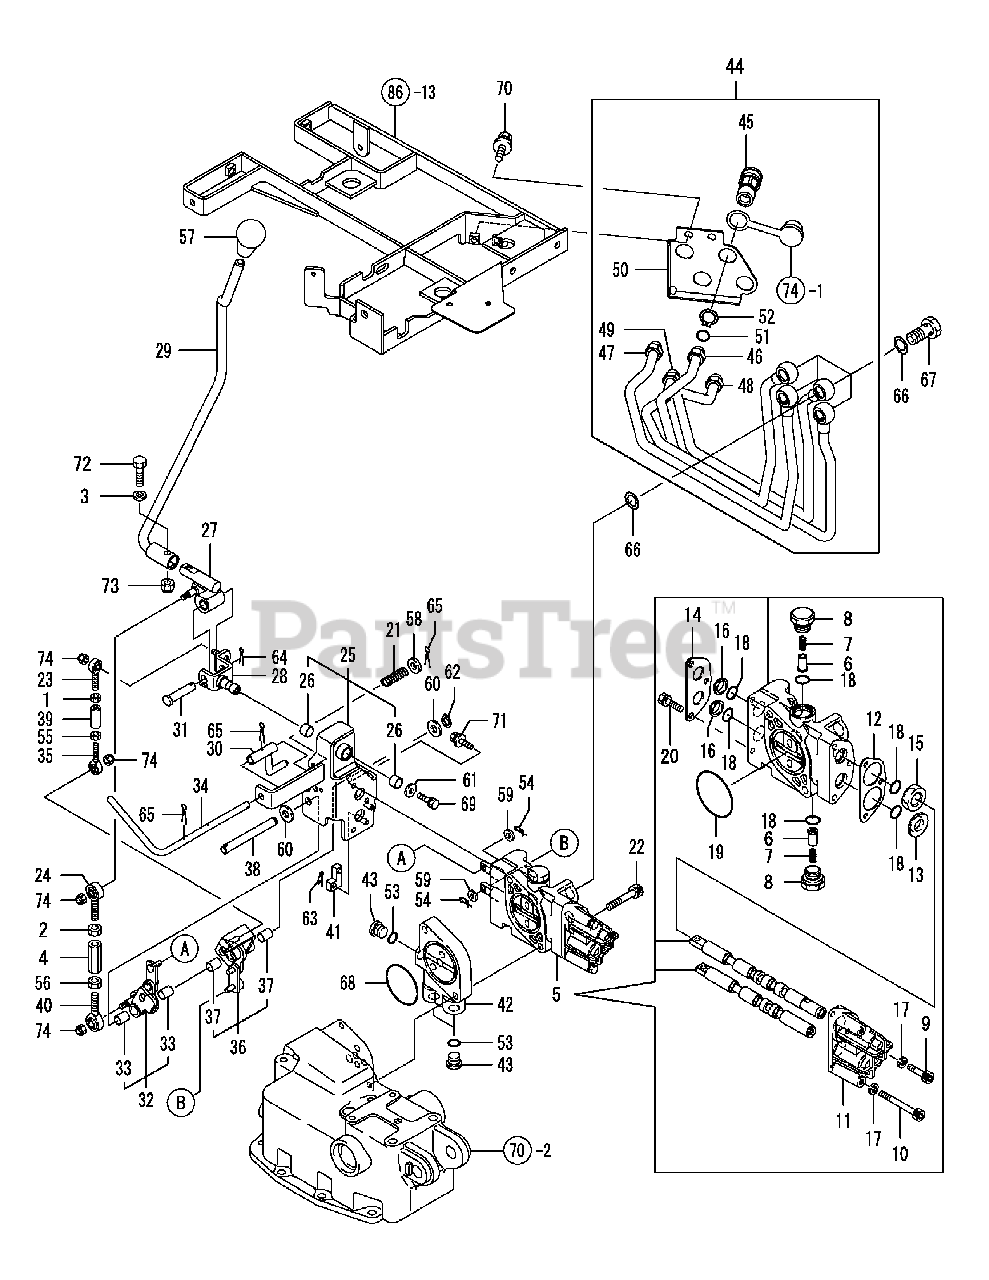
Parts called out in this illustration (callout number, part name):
2	Nut W/Washer 8
3	Washer 8.5X20X3.2
14	Cover, Dust Seal
18	O-Ring 1A P-14.0
19	O-Ring 1A G-50.0
25	Holder Assy, Lever
26	Bush 12X10
27	Lever Kit, Scv
29	Lever, Control Valve
30	Pin Cmp, Stopper
32	Cam Assy, Link L
36	Cam Assy, Link B
38	Shaft, Link Cam
45	Hyd.Quick Coupler
50	Mount, Coupler
54	Pin 6, Come-Off Snap
59	Washer 6, Polished
60	Washer 10,Polished
64	Cotter Pin 2.0X16
65	Cotter Pin 2.5X25
68	O-Ring 1A G-55.0
70	Bolt W/Washer M8X20
72	Bolt M 8X 35 Plated
